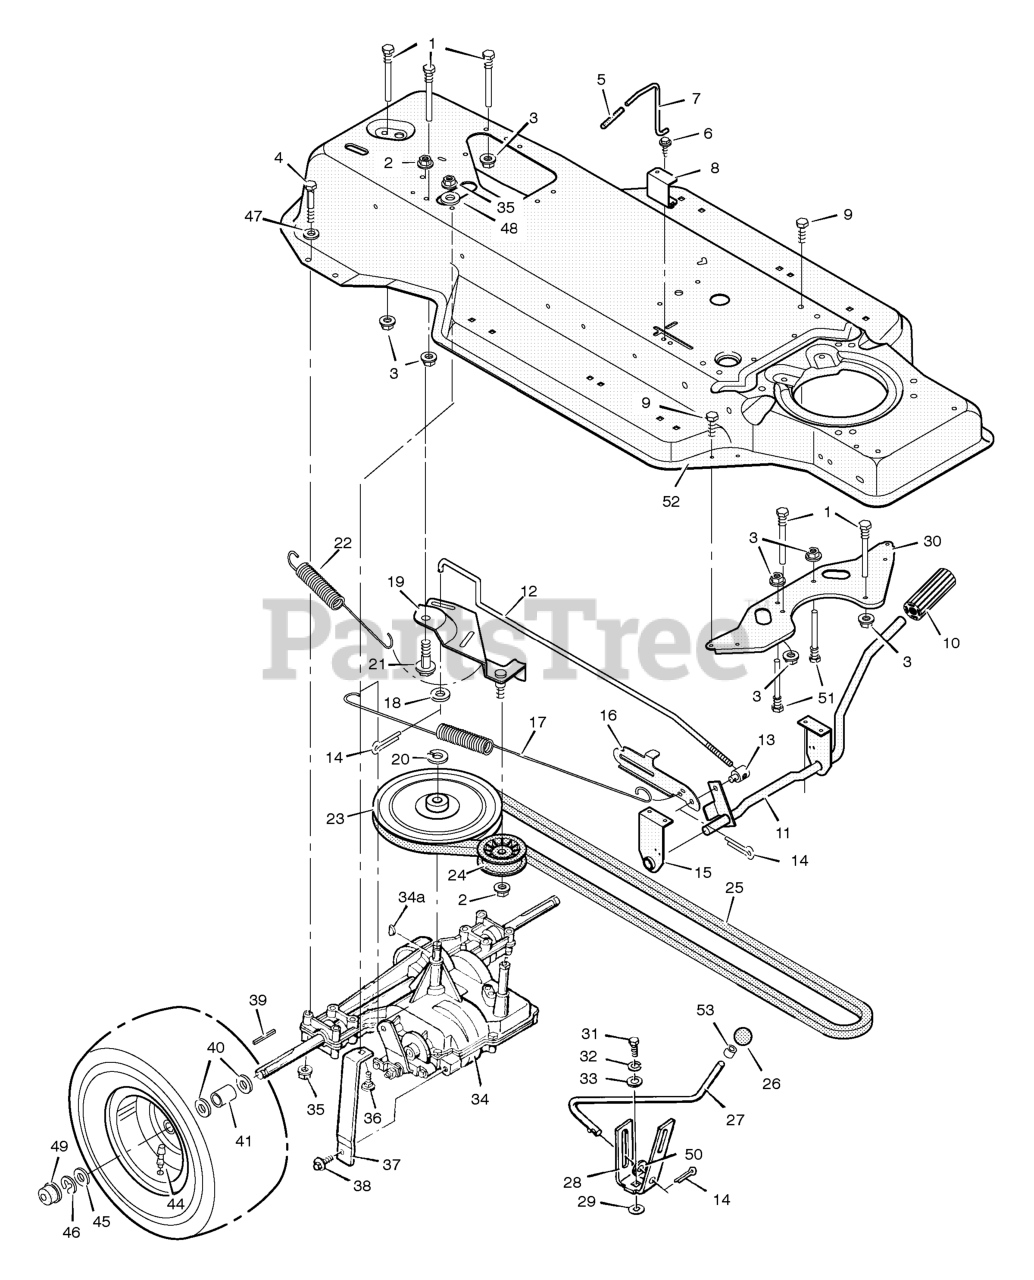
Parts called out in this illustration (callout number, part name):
1	Guide, Belt
2	Locknut, Flange
3	Nut, Flange
4	Bolt, Hex
7	Rod, Control
8	Guide, Bracket
10	Clutch and Brake Pedal
11	Lever Assembly
12	Rod, Clutch
13	Nut, Adjustable
14	Pin, Cotter
15	Bracket, Support
16	Latch, Park Brake
17	Spring, Brake Extension
18	Washer
19	Bracket Assembly, Idler
20	Ring, Retainer
21	Bolt, Shoulder
22	Spring, Drive Extension
23	Pulley, Motion Drive
24	Pulley, Backside Idler
25	Belt, Motion Drive
26	Knob, Shift Lever
27	Lever, Shift
28	Yoke, Shift
30	Plate, Belt Guide
31	Bolt, Hex
32	Lockwasher
34	Transaxle, Peerless **
34A	Woodruff Key No. 9
35	Nut, Flange
36	Bolt, Carriage
37	Support, Transaxle
39	Key, Square
41	Spacer, Transaxle
43	Wheel & Tire Assembly
44	Stem, Valve
47	Washer
49	Hub Cap
50	Washer
51	Guide, Belt
52	Frame Assembly
53	Ring, Tolerance
